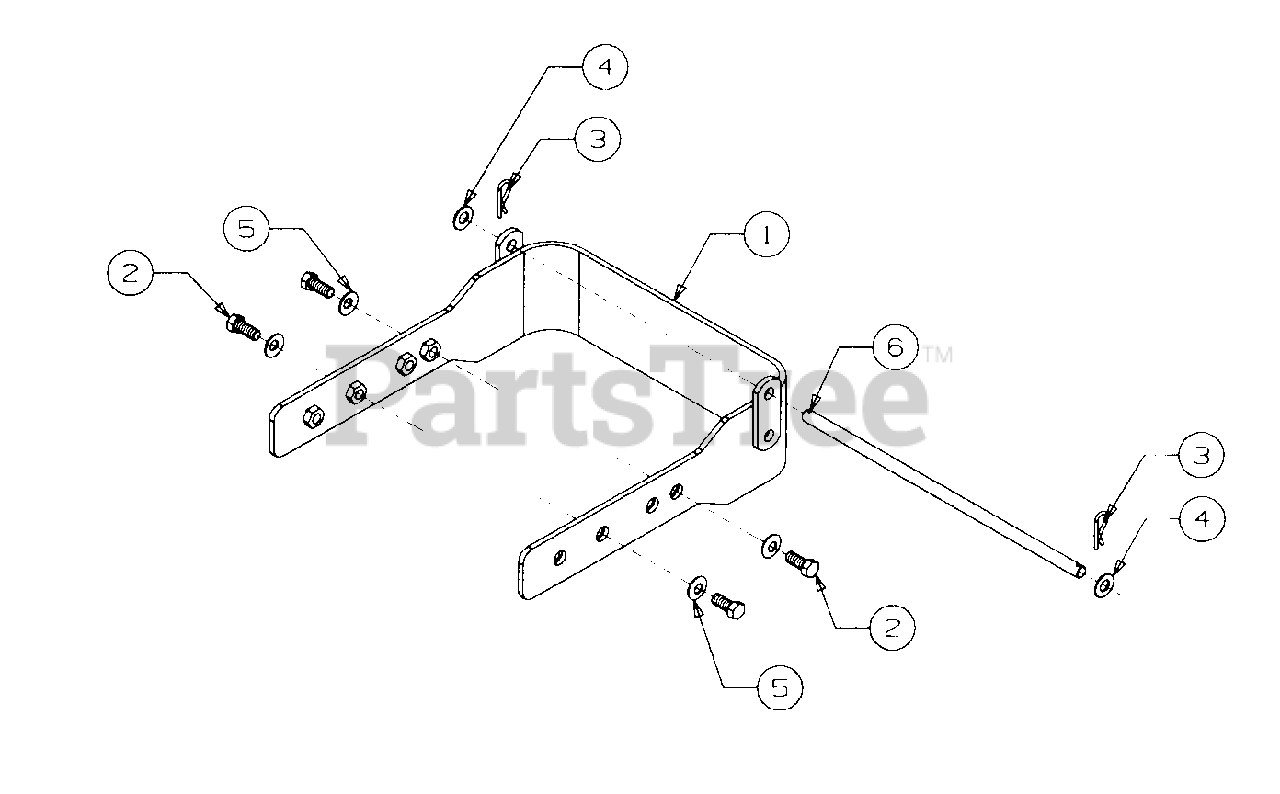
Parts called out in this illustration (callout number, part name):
1	Bracket, Weight
2	Screw, Hex Cap, 7/16-14 x 1.0 Lg
3	Pin, Internal Cotter
4	FLAT WASHER .510X.
5	Washer, Bell, .45 x 1.0 x. 062 Thk
6	Rod, .50 Dia x 15.0 Lg
